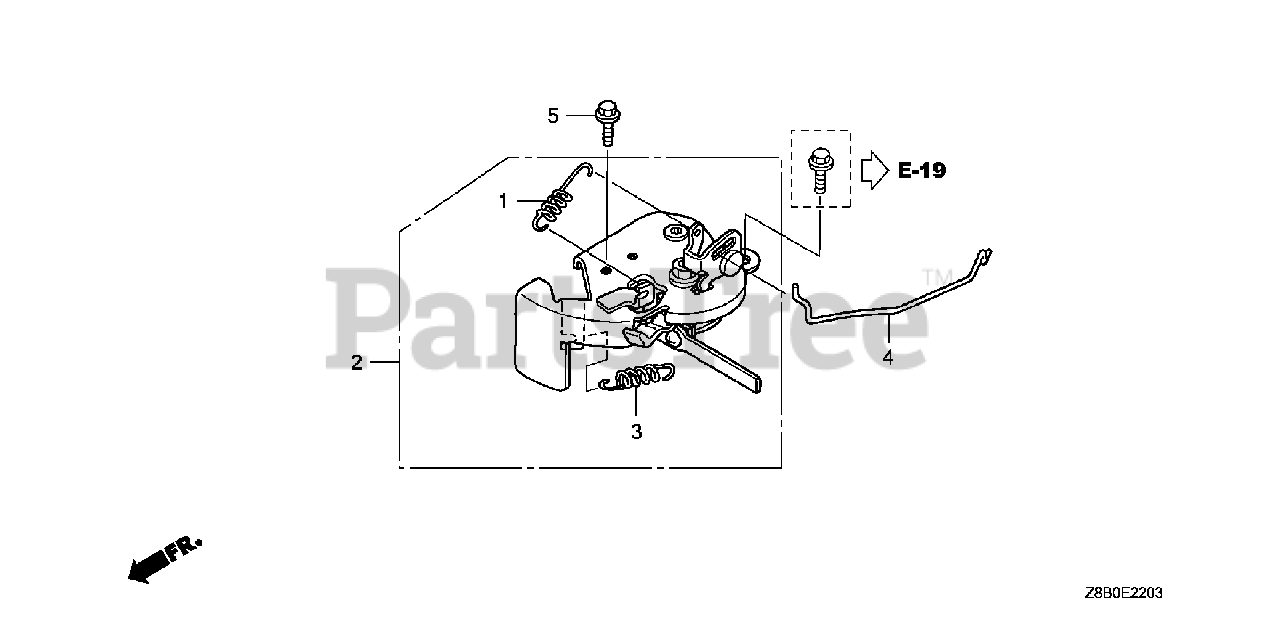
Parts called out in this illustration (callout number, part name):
1	SPRING, RETURN
2	LEVER ASSY., CHOKE
3	SPRING, CHOKE LEVER
4	ROD, STOP
5	BOLT, FLANGE (6X20) (CT200)
